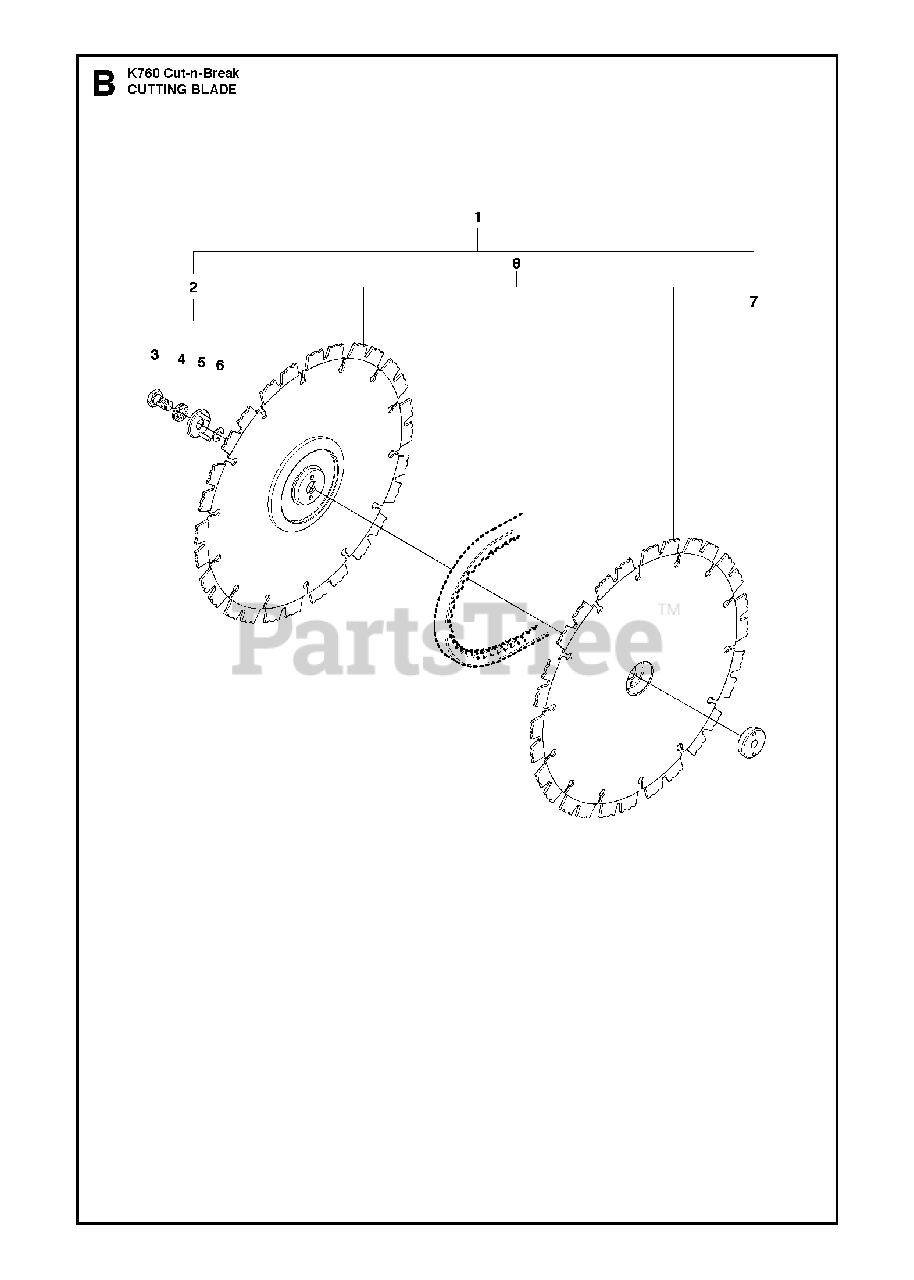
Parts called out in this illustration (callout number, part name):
1	SCREW KITIncl. 2, 7
6	RETAINER RING
8	DIAMOND BLADEEL10 CnB Soft
8	DIAMOND BLADEEL35 CnB Medium
8	DIAMOND BLADEEL70 CnB Hard
